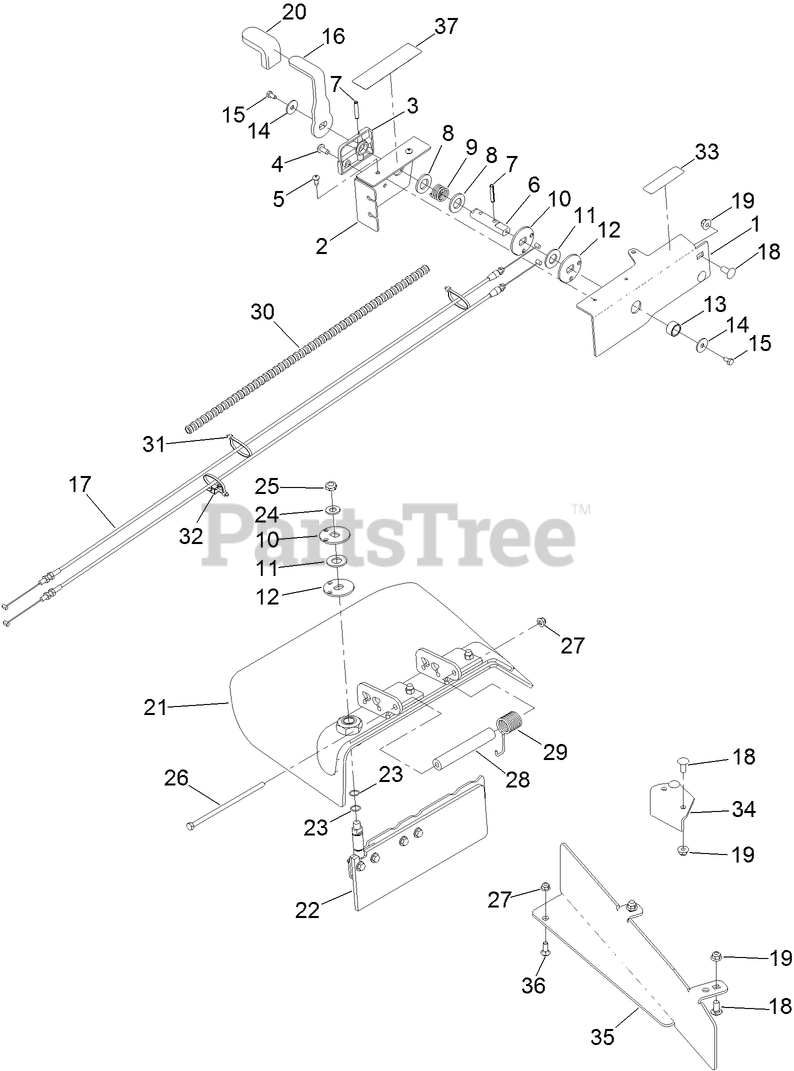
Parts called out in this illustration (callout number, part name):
1	BRACKET-MOUNTING, OCDC
2	BRACKET-COVER
3	BLOCK-DETENT
5	SCREW-TPH THD FORM
6	PIN-PIVOT
7	PIN-ROLL
8	WASHER-FLAT
9	SPRING-COMPRESSION
10	PULLEY-TOP
11	PULLEY-MIDDLE
12	PULLEY-BOTTOM
13	BUSHING
14	WASHER-FLAT
15	SCREW-HH
16	HANDLE-PIVOT
18	SCREW-CARR
19	NUT-HF, NI
20	GRIP-LEVER
21	RUBBER DEFLECTOR ASM
22	ASM-DOOR
23	O-RING
24	WASHER-FLAT
25	NUT-HEX
26	SCREW-HH
27	NUT-HF, NI
28	SPACER
29	SPRING-TORSION
30	TUBE-CONVOLUTED
31	TIE-CABLE
32	MOUNT-TIE, CABLE
33	DECAL-CONTROL, MOTION
34	BAFFLE-DISCHARGE
35	BAFFLE-BAGGER, 48 INCH
36	SCREW-CARR
37	DECAL-CHUTE GATE
